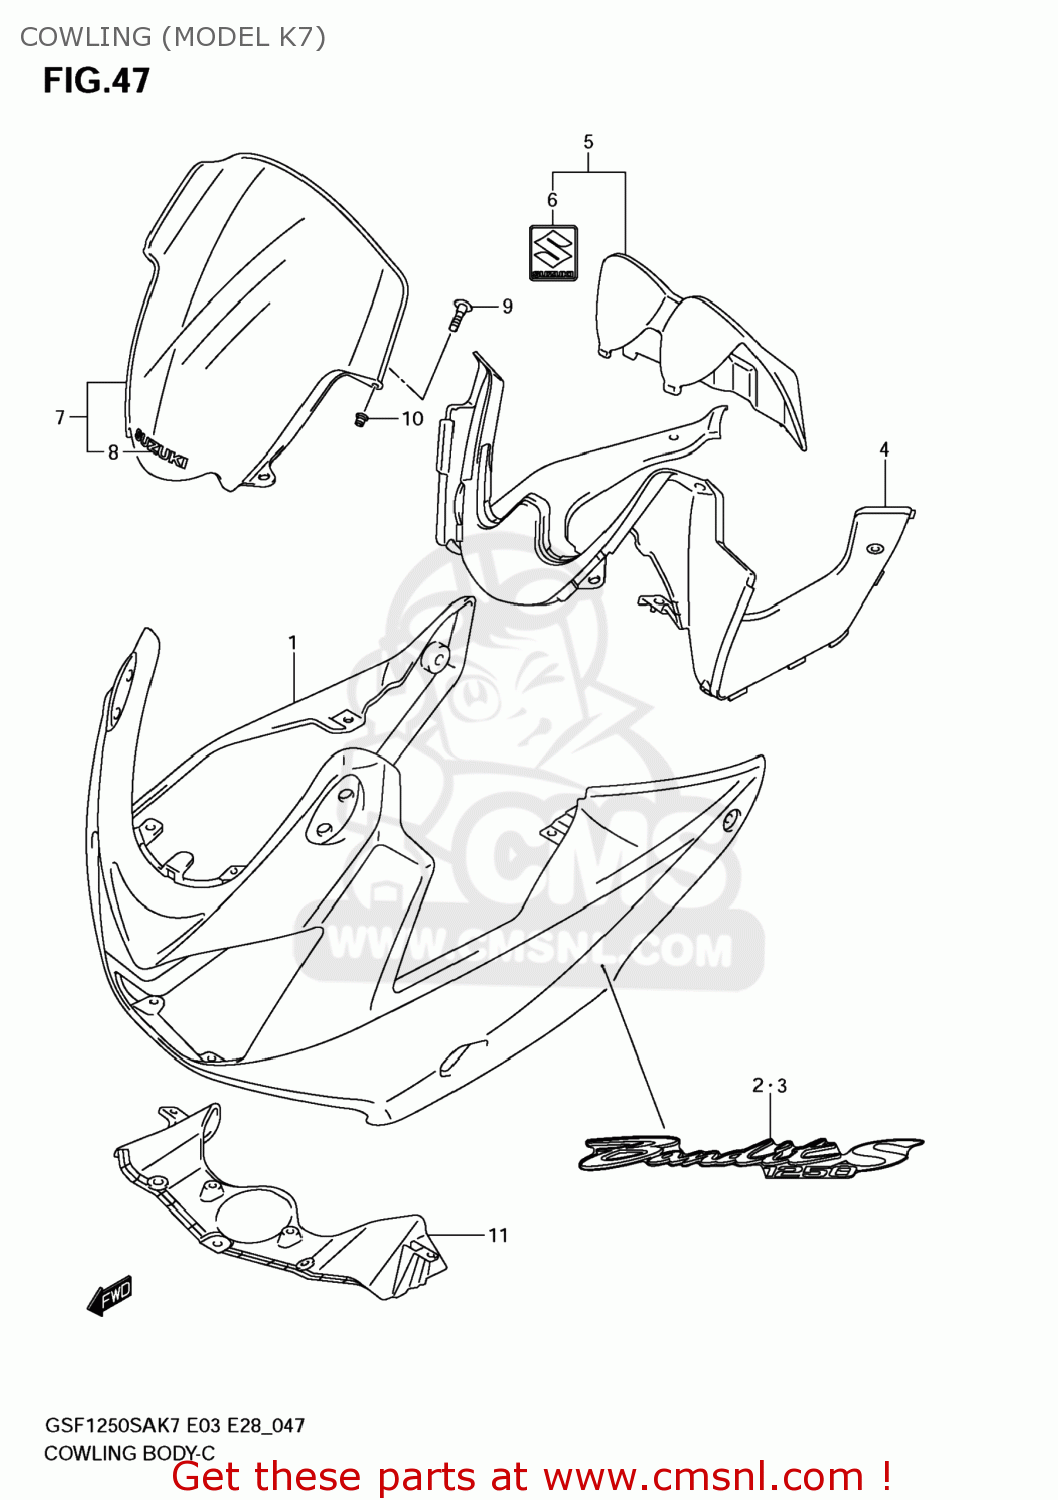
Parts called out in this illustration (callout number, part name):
1	COWLING,BODY(RED)
2	EMBLEM,COWLING BODY SIDE,R
3	EMBLEM,COWLING BODY SIDE,L
4	PANEL,METER
5	LID,METER PANEL
6	EMBLEM,S
7	WINDSCREEN(SILVER)
8	EMBLEM,WINDSCREEN
9	SCREW(5X16)
10	NUT
11	COVER,COWLING INNER
